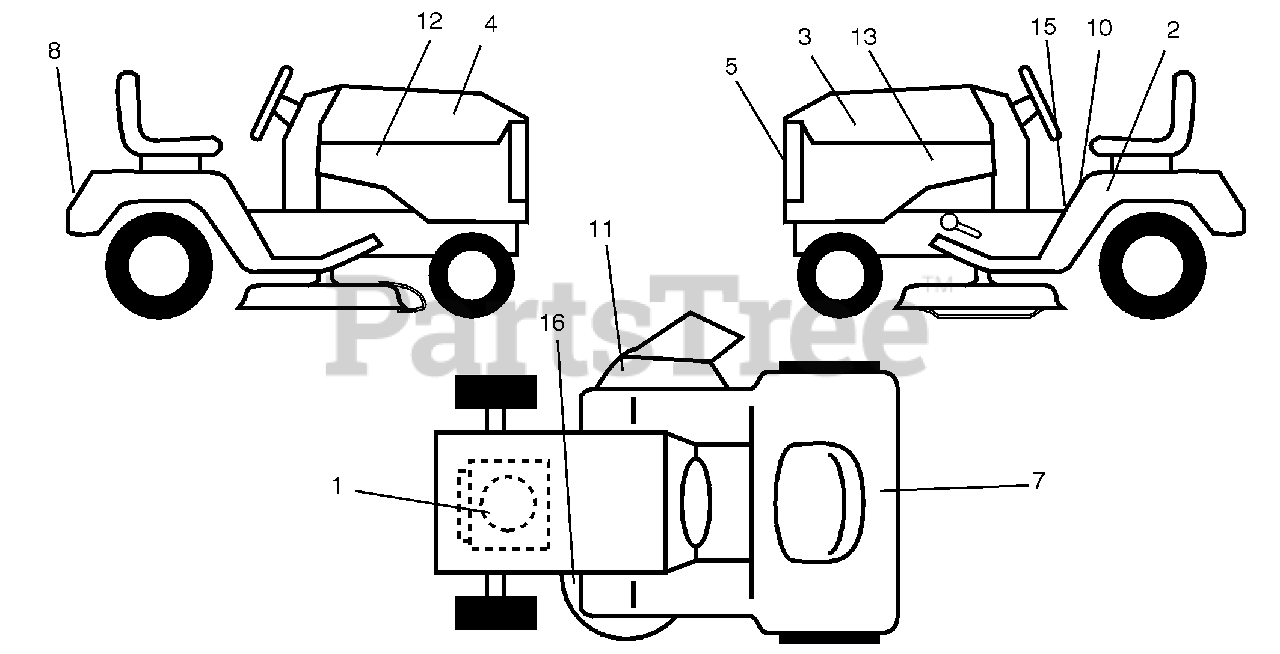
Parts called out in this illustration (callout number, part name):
1	Decal, Engine, HP
2	Decal, Indicator
3	Decal, Hood, L.H.
4	Decal, Hood, R.H.
5	Decal, Logo, Grill
7	Decal, Caution Battery
8	Decal, Logo, Fender
10	Decal, Fender, Caution
11	Decal, Warning, Multi-Language
12	Decal, Hood, Insert, R.H.
13	Decal, Hood, Insert, L.H.
15	Decal, Instruction, Operating
16	Decal, V-Belt Schematic
CR38	Grass Catcher
MK380	Mulch Kit
